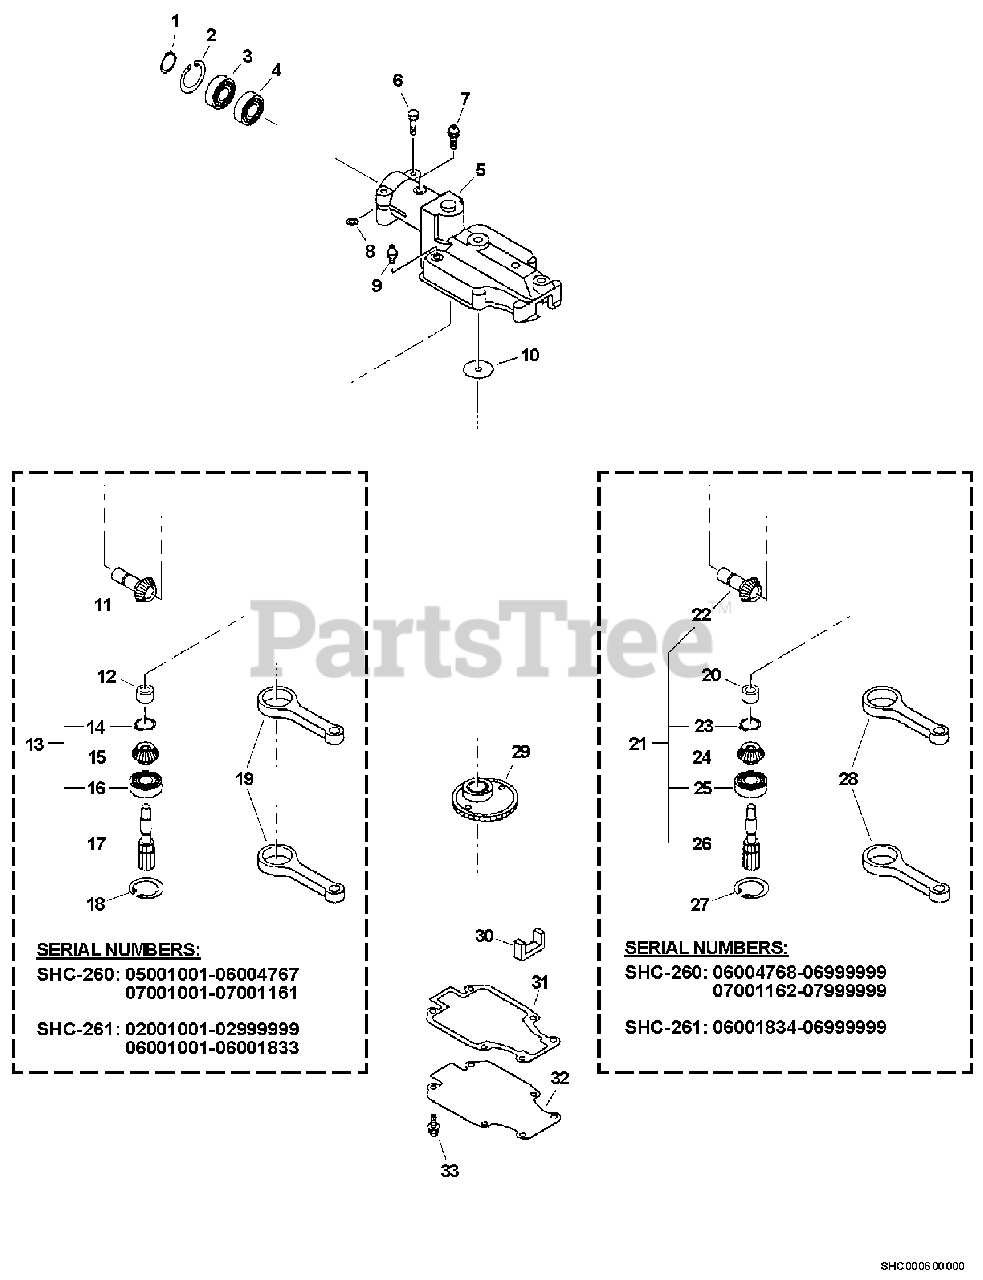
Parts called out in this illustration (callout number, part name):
1	RING, SNAP Ø12
2	RING, RETAINING Ø24
3	BEARING, BALL 6901Z
4	BEARING, BALL 6901
5	CASE, GEAR
6	BOLT 5×28
7	BOLT 5×12
9	FITTING, GREASE
11	GEAR, BEVEL
12	BEARING, NEEDLE
13	SPUR GEAR ASSY
14	RING, RETAINING
15	GEAR, BEVEL - DRIVEN
16	BEARING, BALL 6901
17	GEAR, PINION
18	RING, RETAINING Ø24
19	ROD, CONNECTING
20	BEARING, NEEDLE
21	GEAR KIT, SPUR
22	GEAR, BEVEL
23	RING, RETAINING
24	GEAR, BEVEL
25	BEARING, BALL 6901
26	GEAR, PINION
27	RING, RETAINING Ø24
28	CONROD
31	GASKET, GEAR CASE
32	LID, GEAR CASE
33	BOLT 4×12
